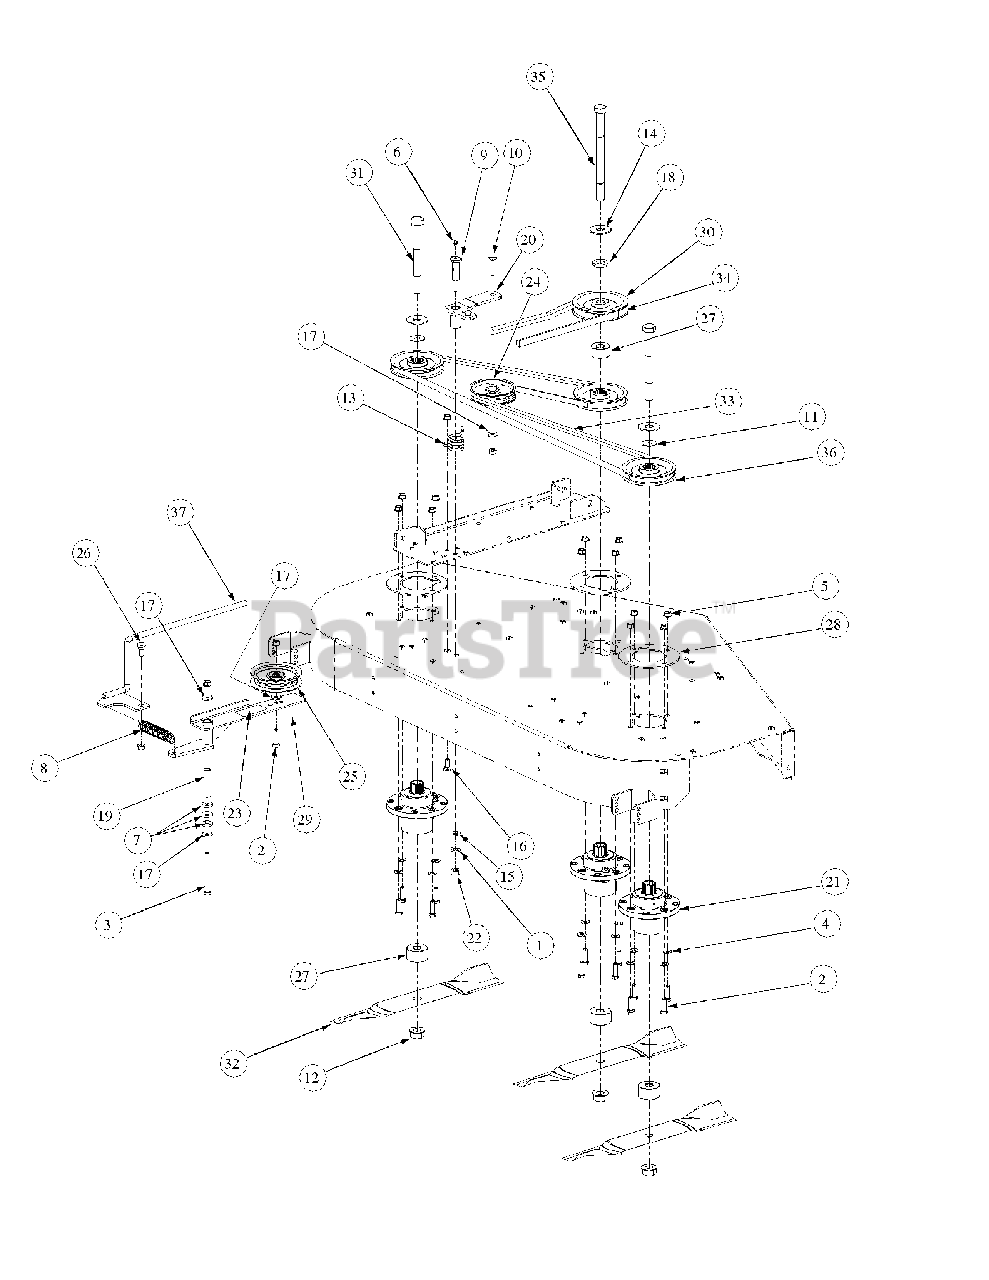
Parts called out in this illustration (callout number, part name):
1	Lock Washer, 7/16
2	Hex Cap Screw, 3/8-16 x 1-1/4
3	Hex Cap Screw, 3/8-16, 4.00
4	Flat Washer, 3/8
5	Hex Nut, Flange Lock, 3/8-16
6	Grease Fitting, 1/4-28 x 3/16
7	Idler Washer
8	Extension Spring, 1.0 OD x 5.125
9	Shoulder Screw, 7/16-14
10	Hex Carriage Screw, 3/8-16, 1.75
11	Spacer, .812 ID x .218 LG
12	Flange Hex Nut, 3/4-16
13	Torsion Spring Idler
14	Flat Washer, .781 ID, 2.00 OD, .105
15	Flat Washer, .469 ID, .875 OD, .105
16	Carriage Bolt, 3/8-16 x 1
17	Flat Washer, .406 ID, 1.0 OD, .105
19	Spacer, .39 ID x .625 OD x 2.75
20	Idler Arm Assembly, Deck Spindle
20	Bearing
21	Spindle Assembly, Aluminum Fab Deck
22	Hex Nut, 7/16-14
23	Decal, Idler Location
24	Flat Pulley
25	Idler Pulley, 4.06 OD w/Deep Plan Flanges
26	Shoulder Screw, .50 x .27 LG, 3/8-16
27	Spacer, .760 ID x 2.000 OD x 1.1
28	Plate Support, Cast Aluminum Spindle
29	Idler Arm Assembly, Flat Top Bearing
30	V Pulley, 5.25 OD
31	Hex Cap Screw, 3/4-16, 7.00
32	Hi-Lift Blade, 19.0, 0.756
33	V Belt, A Section x 114.3
34	V Belt, B Section x 87.3
35	Hex Cap Screw, 3/4-16, 9.00
36	V Pulley, 5.00 OD
37	Rod Fab Deck Spring Tension
